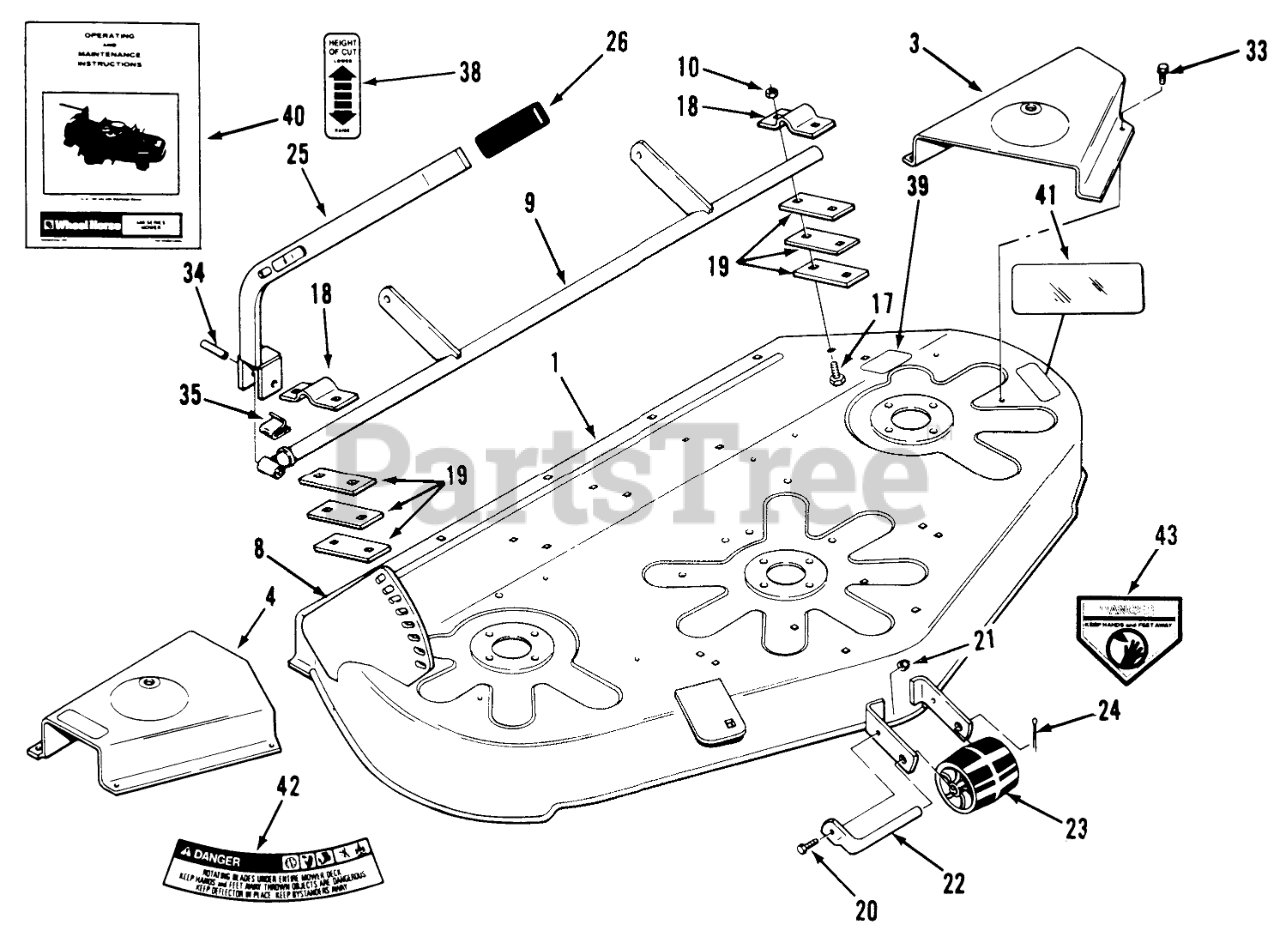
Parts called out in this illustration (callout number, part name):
1	Deck-Mower
3	Belt Cover LH
4	Belt Cover RH
8	QUADRANT 42RY MOWER
9	Lift Support
10	NUT
17	Bolt
19	Bar
20	Bolt
21	Nut
22	ROLLER-SHAFT
23	Roller
24	Cotter Pin
25	Lever
33	Bolt
34	SPIROL PIN 3/8X1 1/2
35	CLIP-SPRING
38	DECAL-HOC
40	Manual-Operators
41	DECAL-OVERLAY
42	DECAL - DANGER
43	DECAL-DANGER
